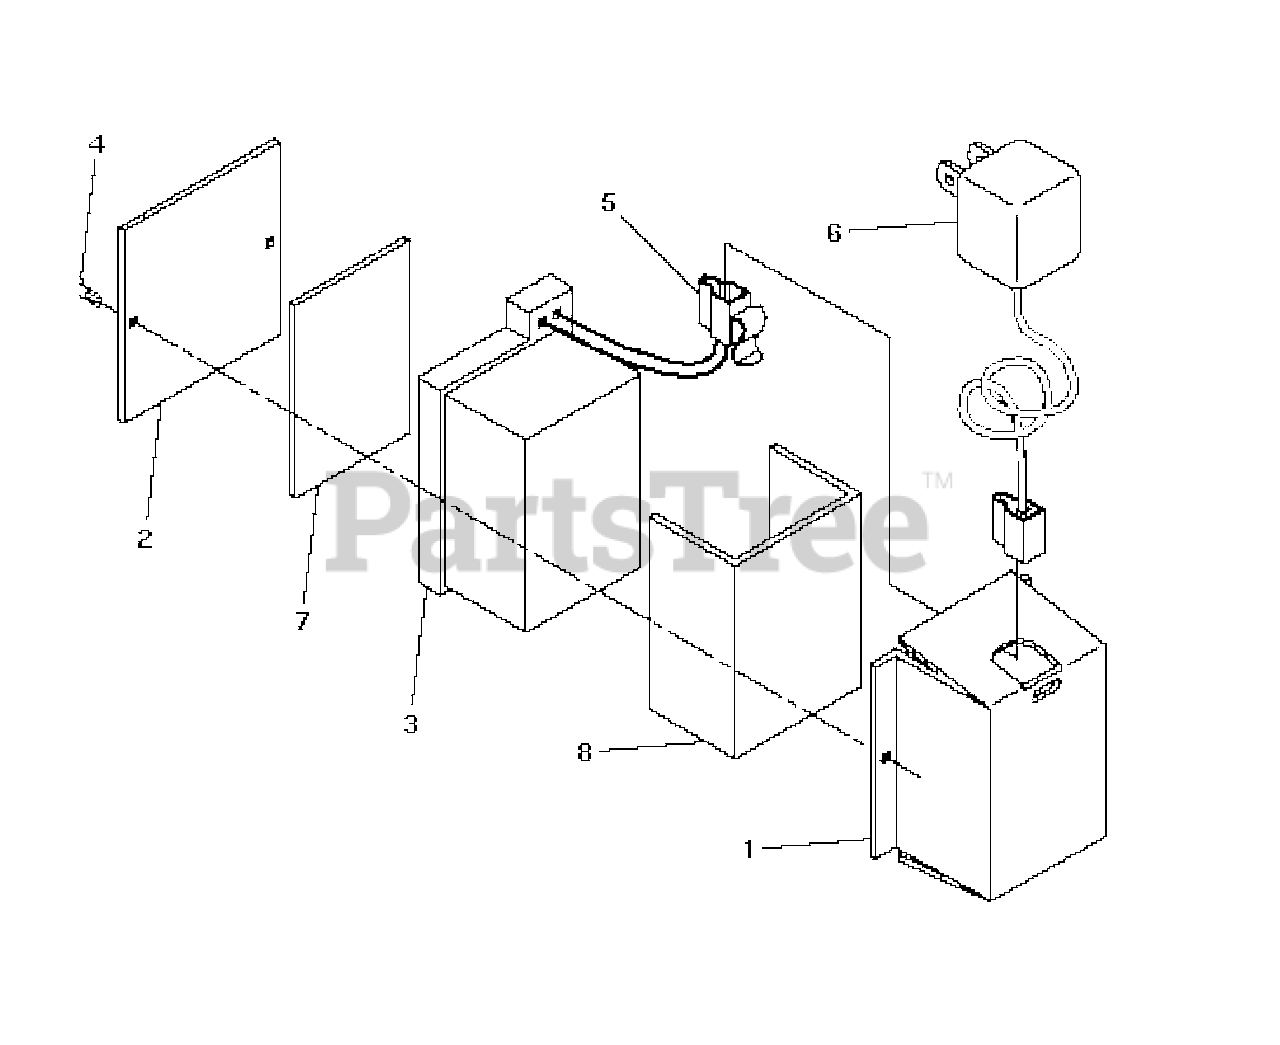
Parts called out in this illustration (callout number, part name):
1	Battery Bracket
2	Battery Cover
3	Battery Kit
4	Hex Washer Head Screw #10-24 x 1/2
5	Connector Mounting Clip
6	Battery Charger
7	Battery Pad
8	Battery Wrap
